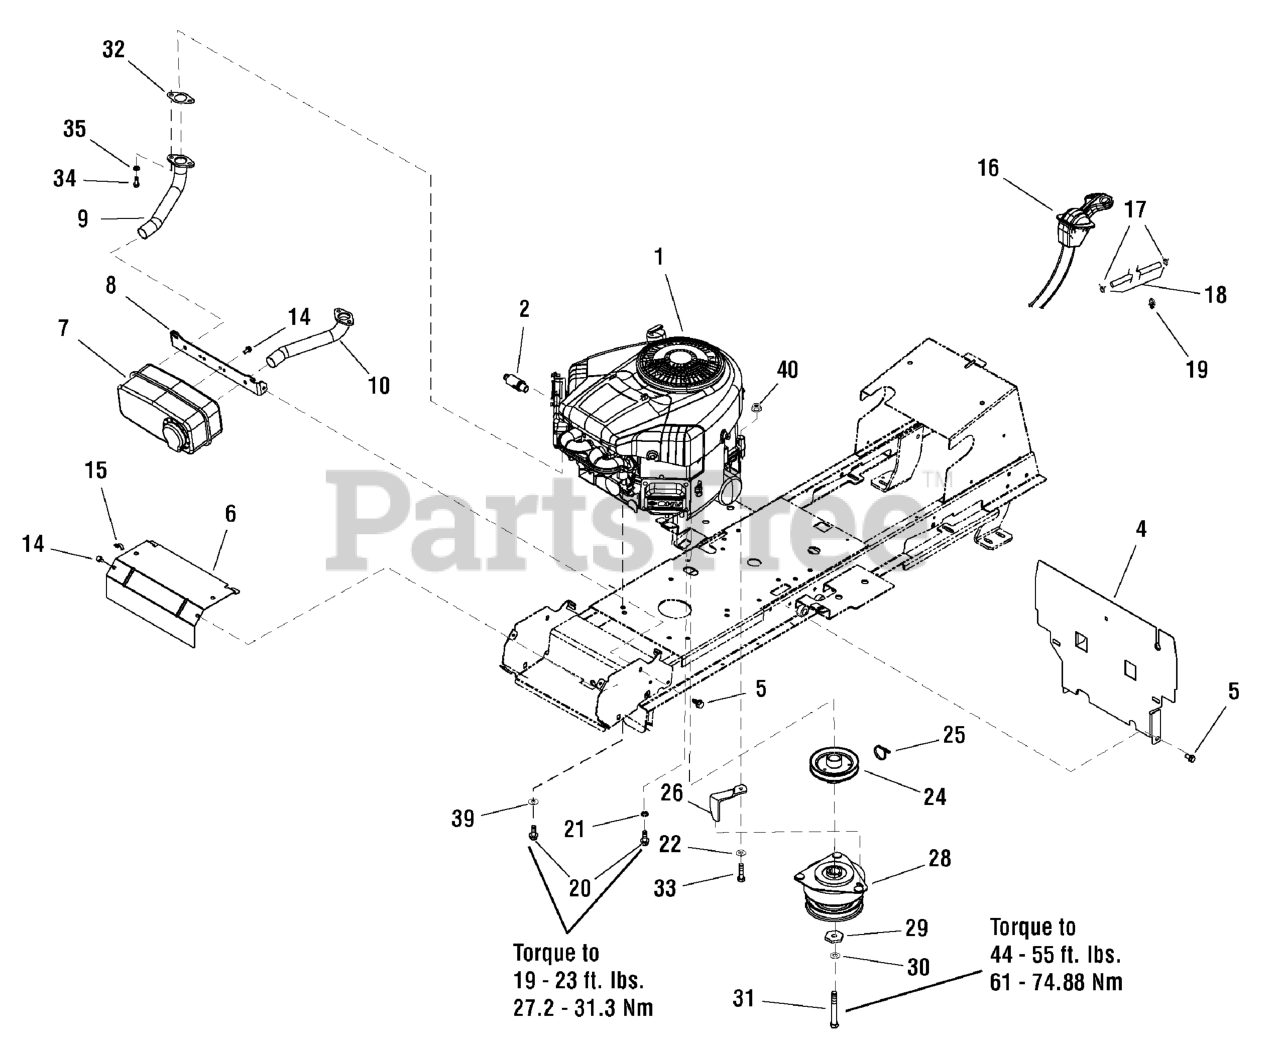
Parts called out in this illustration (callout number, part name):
1	* ENGINE, 18HP Briggs & Stratton, V-Twin Intek
2	VALVE, Shut Off Oil Drain
4	SHIELD, Heat Change
5	CAPSCREW, Hex Washer Head, Taptite, 5/16-18 x 5/8
6	HEAT SHIELD, Engine
7	MUFFLER, Twin
8	SUPPORT, Muffler
9	PIPE, Exhaust
10	PIPE, Exhaust
14	CAPSCREW, Hex Washer Head, Taptite, 1/4-20 x 1/2
15	CLIP, Wire
16	CONTROL, Throttle
18	HOSE, Fuel
19	CLIP, Hose
20	CAPSCREW, M8 x 35
21	LOCKWASHER, External Tooth, 3/8
22	WASHER, 9
24	PULLEY & HUB ASSEMBLY, Engine
26	RETAINER, Clutch
28	CLUTCH, Electric
29	WASHER, Hex
30	LOCKWSHER, Spring, 7/16
31	CAPSCREW, Hex Head, 7/16-20 x 3-1/2
32	GASKET, Exhaust
33	CAPSCREW, M8 x 45
34	CAPSCREW, Hex Socket Head, 5/16-18 x 3/4
35	LOCKWASHER, Spring, 5/16
39	WASHER, 8.4
